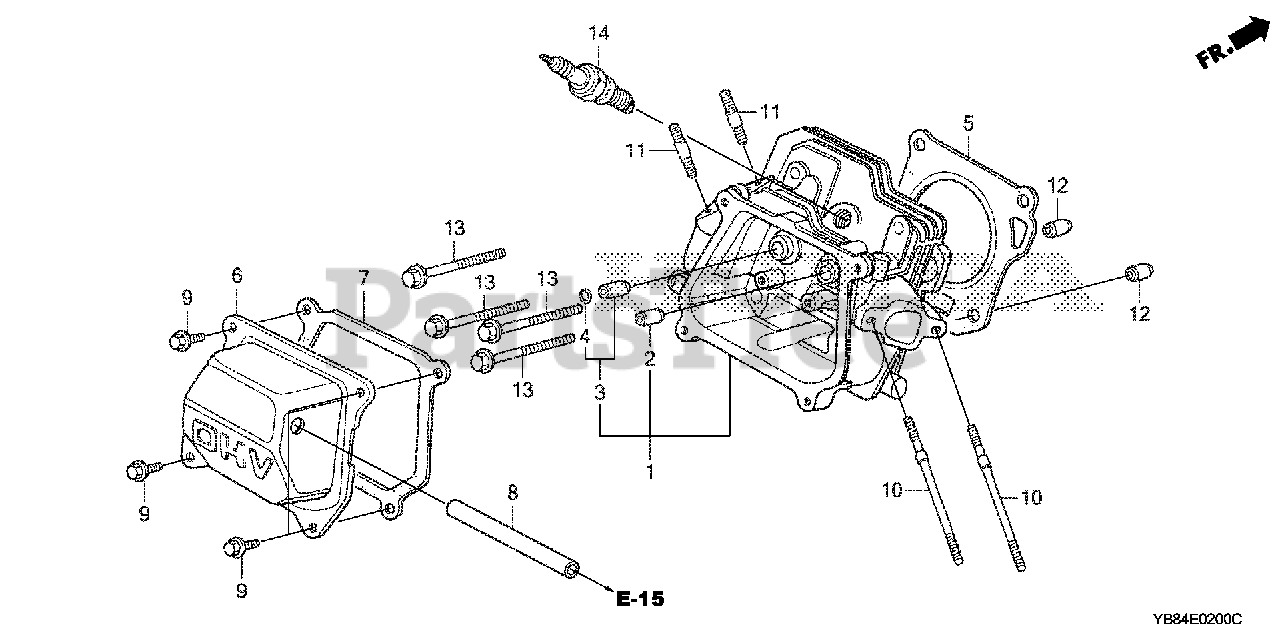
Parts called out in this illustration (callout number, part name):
1	CYLINDER HEAD
2	GUIDE, VALVE (OVER SIZE)
3	GUIDE, EX. VALVE (OVER SIZE)
4	CLIP, VALVE GUIDE
5	GASKET, CYLINDER HEAD (NIPPON LEAKLESS)
6	COVER, HEAD
7	GASKET, HEAD COVER
8	TUBE, BREATHER
9	BOLT, FLANGE (6X12) (CT200)
10	BOLT, STUD (6X112)
11	BOLT, STUD (8X32)
12	PIN, DOWEL (10X16)
13	BOLT, FLANGE (8X60)
14	SPARK PLUG (BPR6ES) (NGK)
14	SPARK PLUG (W20EPR-U) (DENSO)
